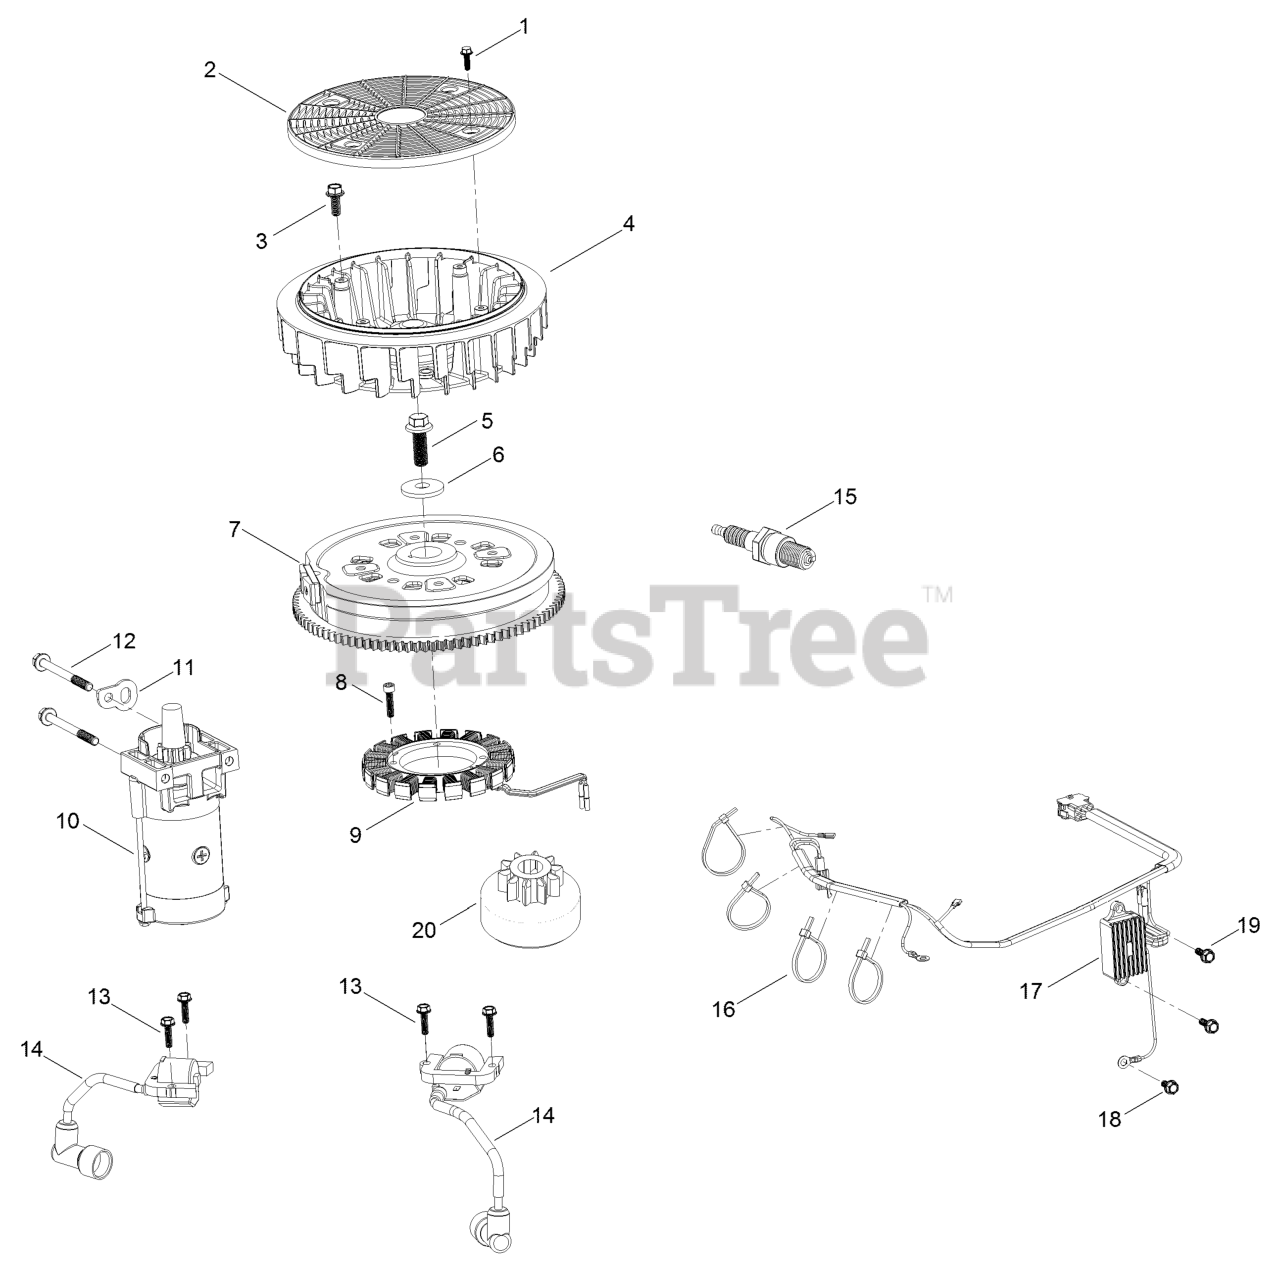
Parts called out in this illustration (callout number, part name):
1	SCREW-HWH
2	SCREEN-ROTATING
3	SCREW-HWH
4	FAN-COOLING
5	SCREW-HWH
6	WASHER-FLAT
7	FLYWHEEL
8	SCREW-HSH
11	BRACKET-LIFT
12	SCREW-HHF
13	BOLT-FLANGE
15	SPARK PLUG
16	TIE-ZIP
17	REGULATOR-VOLTAGE W/HARNE
18	SCREW-HHF
19	SCREW-HHF
20	PINION-STARTER
